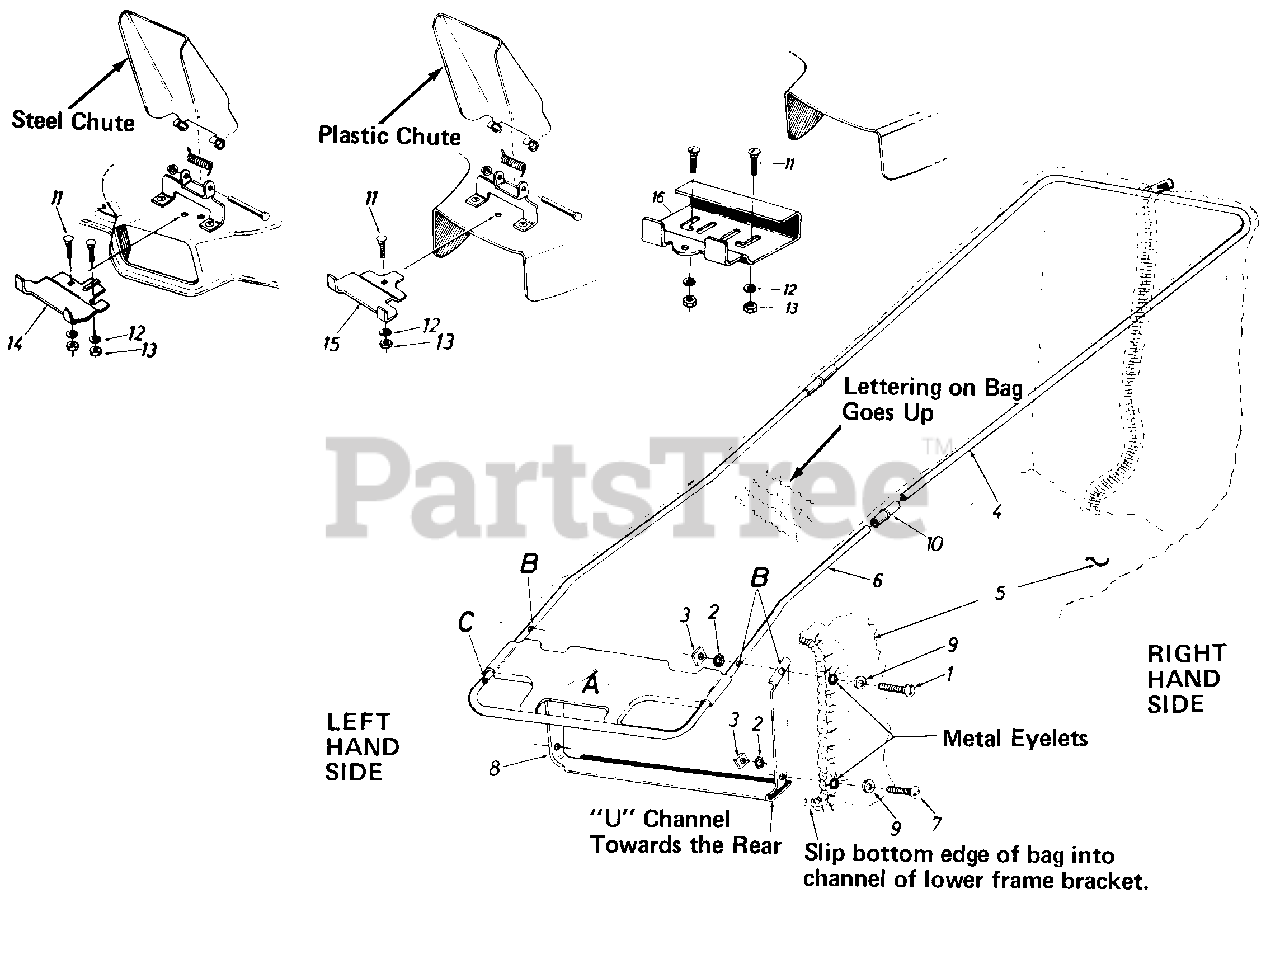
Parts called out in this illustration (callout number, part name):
1	Truss Mach. Scr. #10-24 x 1.00" Lg.*
2	Ext. L-Wash. #10 Scr.*
3	Sq. Nut #10-24 Thd.*
4	Frame-Upper Half
5	Grass Catcher Bag
6	Frame-Lower Half
7	Truss Mach. Scr. #10-24 x .62" Lg.*
8	Lower Frame Bracket
9	Fl.-Wash. .203 I.D. x .41 O.D.
10	Tubing Connector
11	Carriage Bolt
12	LockWasher1/4" I.D.*
13	Hex Nut 1/4-20 Thd.*
14	Adapter Plate
15	Adapter Plate
16	Adapter Plate
